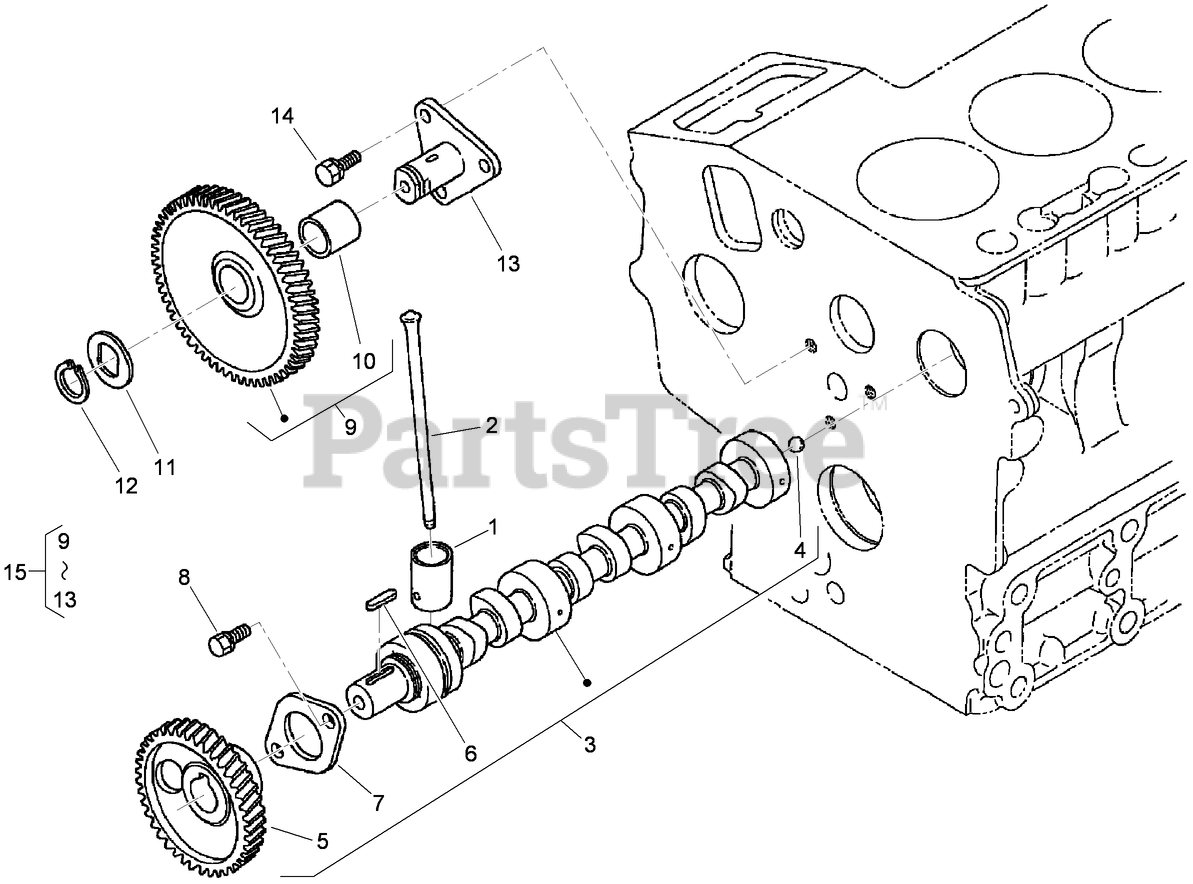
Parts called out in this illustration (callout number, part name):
1	TAPPET
2	ROD-PUSH
3	CAMSHAFT ASM
5	GEAR-CAM
6	KEY-FEATHER
7	STOPPER-CAMSHAFT
9	GEAR-IDLE
10	BUSHING
11	COLLAR-GEAR, IDLE
12	RING-SNAP
13	SHAFT-GEAR, IDLE
15	IDLE GEAR ASM
